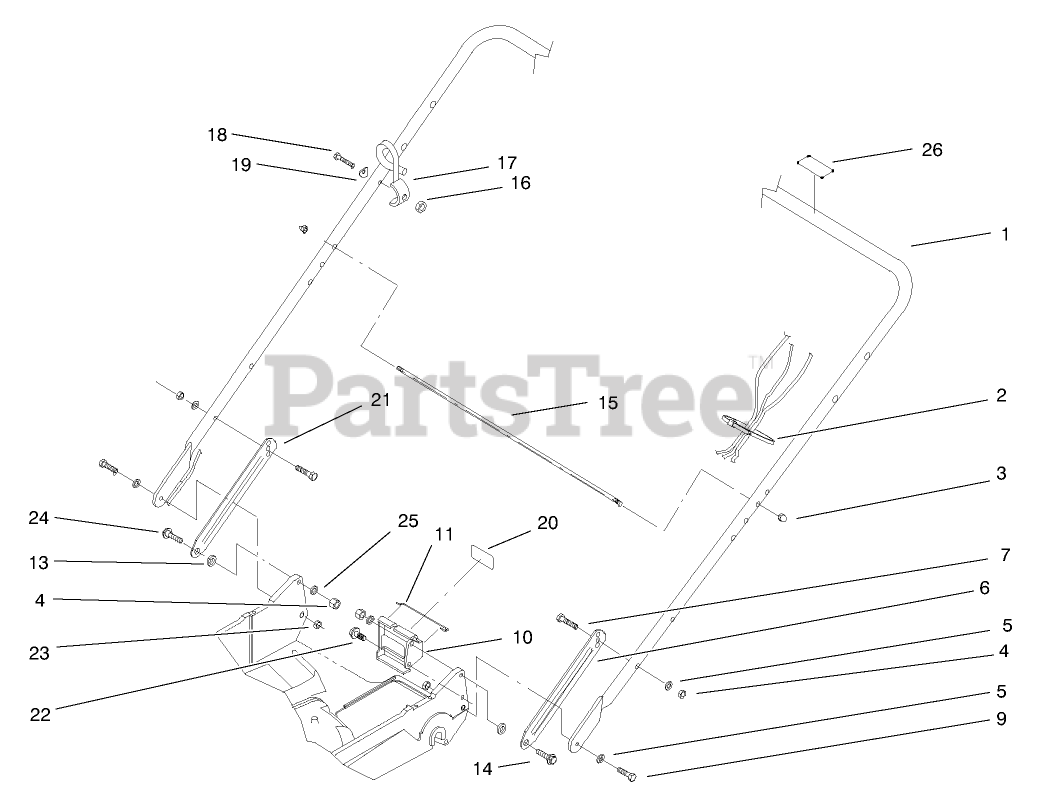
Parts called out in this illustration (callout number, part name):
2	TIE-CABLE
3	NUT-CAP
4	NUT-LOCK, NI
5	WASHER-BELLEVILLE
6	LATCH-HANDLE, LH
7	SCREW-HH
9	SCREW-HH
10	BRACKET-ADJUSTMENT, TRACTION
11	RETAINER-CABLE
13	SPACER
14	SCREW-SHOULDER
15	ROD-SUPPORT, BAG
16	NUT-LOCK, NI
17	GUIDE-ROPE
18	SCREW-HH
19	WASHER
20	DECAL-POSITION, GEAR
21	LATCH-HANDLE, RH
22	SCREW-HWHTF
23	NUT-LOCK, NI
24	SCREW-SHOULDER
25	WASHER-PLAIN
26	DECAL-PROTECTION, EAR
